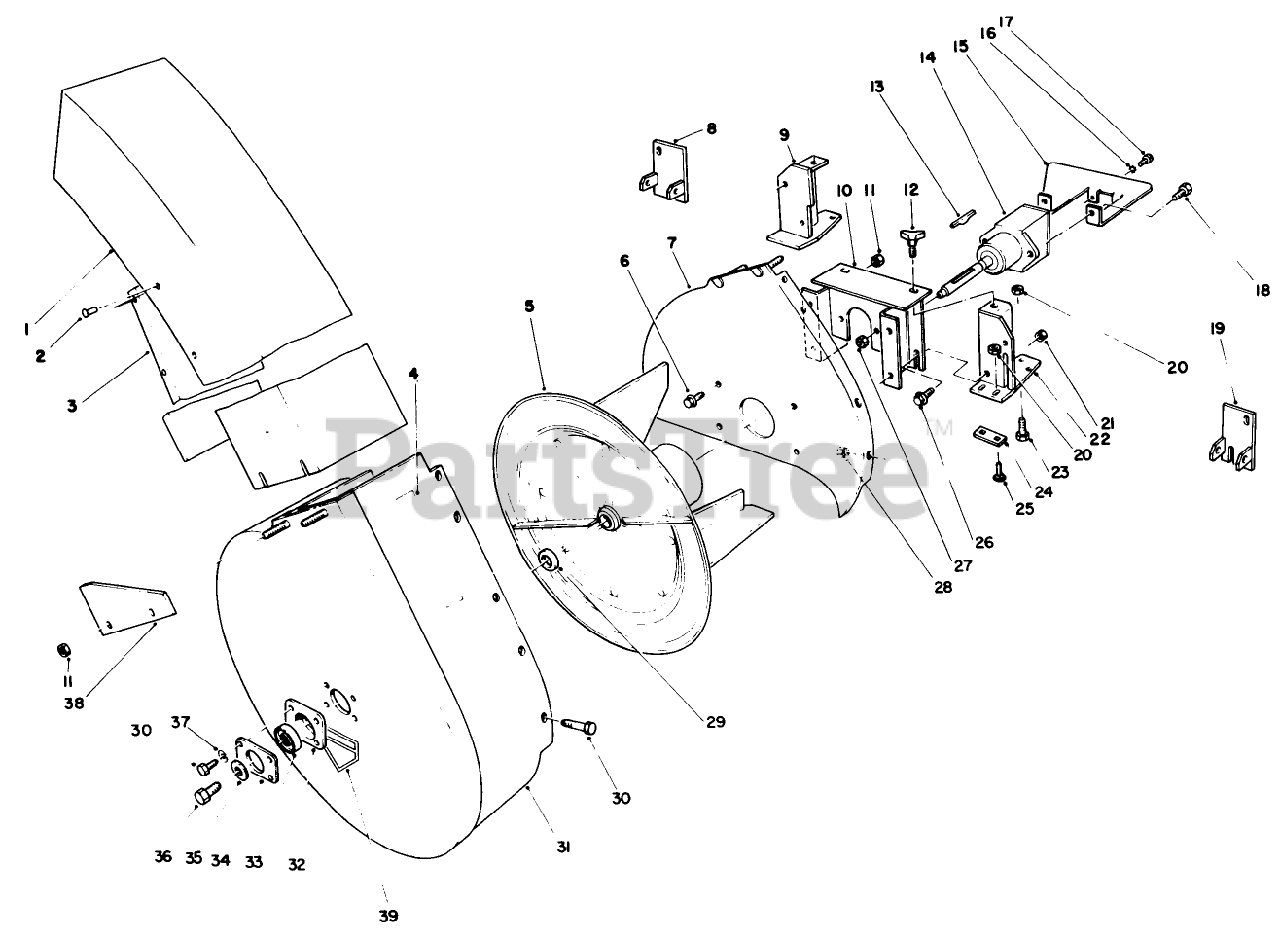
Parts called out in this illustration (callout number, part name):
1	CHUTE ASM
6	SCREW-HHF
9	LH BRACKET ASM, WELDED
11	NUT-LOCK, NI
16	WASHER-LOCK, EXT
18	SCREW-HH
20	NUT-LOCK, CONE
21	NUT-JAM
22	RH BRACKET ASM, WELDED
23	SCREW-HH
25	BOLT-CARR
26	SCREW-HHF
27	NUT-LOCK, NI
28	NUT-LOCK, NI
29	SPACER-BEARING
30	SCREW-HH
31	BLOWER HOUSING ASM
32	CUP-BEARING
33	BEARING-BALL
35	SPACER
36	SCREW-HH, LOCK
37	SCREW-HH
39	DECAL-DANGER
